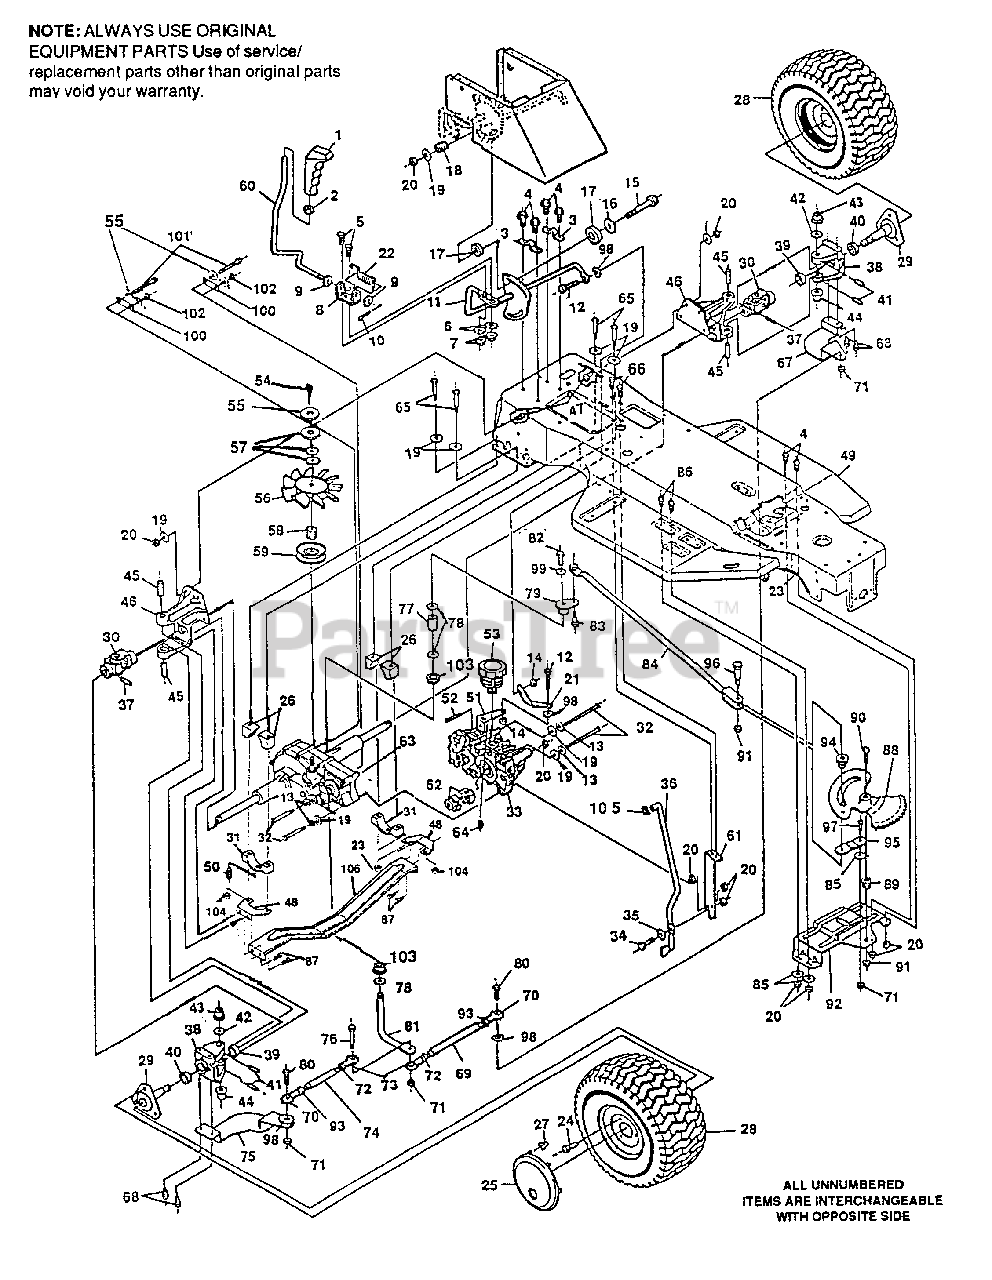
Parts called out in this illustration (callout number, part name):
1	Handle, Deck Engage Lever
2	Nut, 1/2-13 Jam
3	Bracket, Clutch/Brake Arm
4	Screw, 5/16-18 x 1/2 In.
5	Screw, 1/4-20 x .62 In.
6	Flatwasher
7	Nut, 1/4-20
8	Bracket, Shift
9	Washer, Flat
10	Pin, Cotter
11	Shift Rod Assembly
12	Screw, 3/8-16 x 1-1/4 In
14	Nut, 3/8-16 Thd
15	Screw, 5/16-18 x 2 In
16	Washer, Flat
17	Washer, Friction
19	Washer, Flat
20	Nut, 5/16-18 Thd
21	Shift Link
22	Spring, Torsion
23	Trim
24	Screw, Hx Hd, 1/2-20 x 1/2 In
25	Hubcap, 8 In
26	Mounting Block
27	Clip, Hubcap
28	Tire and Wheel Assembly
28	Tire, 15X6.0X6
28	Valve System
29	Hub Assembly
30	U-Joint Assembly
31	Mounting Block
32	Screw, 5/16-18 x 4-1/2 In
33	Hydrostatic Pump
34	Shoulder Bolt
35	Washer
36	Rod- Relief Valve
37	Pin, Grooved, 1/4 x 1 1/2 In
38	Bracket, Steering Pivot, Outer
41	Pin, Spring 1/4 x 1 1/2 In
42	Washer, Flat
43	Bushing, Shouldered
44	Bushing, Shouldered
45	Pin, Steering Hinge
46	Bracket, Steering Pivot, Inner
47	Screw, Hx Hd , 5/16-18 x 1 In
48	Bracket, Transaxle Mounting
49	Main Frame
50	Screw, #10-32 x 1 /4 In
51	Armspeed Control
52	Pin, Spring
53	Reservoir, Hydro
54	Screw, 1/4-20x.62 Hhc
55	Washer, Split Lock
57	Washer, flat .28x1.38x.07
58	Nut, Pulley 1/2-20 and 1/4-20
59	Pulley, Assy. Hydro
61	Stabilizer Bracket
63	Transaxle
65	Screw, 5/16-18x2 50 Hhc
66	Screw, 5/16-18x 63 Hhc
67	Arm, Rear Wheel Steer, L.H.
68	Screw, 3/8-16x1 00 Wahhtap Blk
69	Tie Rod, L.H.
70	Tie Rod End, L.H.
71	Nut, Hex, Ctrlk, 3/8-24
72	Nut, Hex Jam, 3/8-24
74	Tie Rod End, R.H.
75	Arm, Rear Wheel Steer, R.H.
76	Screw, 3/8-24 x 1 3/4 In
78	Washer, Flat 49/64 In
79	Steering Pivot
80	Screw, 3/8-24 x 1 1 /4 In
81	Shaft, Steering Pivot
82	Screw 5/16-24 x 1 In
83	Bolt, Shoulder 3/8-24
84	Rod Assembly, Rear Wheel Steer
85	Washer, Flat 3/8 In
86	Screw, Self-Tap 5/16-18 x 3/8 In
87	Screw, 5/16-18x 88 Wahhtap
88	Assembly Sector Gear
89	Bushing, Sector Gear
90	Screw, 1/2-20 x 2 3/8 In
91	Nut, Hx, Ctrlk 1/2-20
92	Plate, 4-Wheel Steer Pivot
93	Nut, Jam 3/8-24
94	Cam Yoke Roller
95	Arm, Roller Swing
96	Shoulder Bolt, Cam Roller
97	Shoulder Bolt, Cam Follower Arm Pivot
98	Washer, Split Lock
99	Washer Flat
100	Bracket, Rear Pivot
101	Screw 1/4-20 x 3/4 In
102	Nut 1/4-20
103	Bearing Spindle
104	Nut, 5/16-18 Locknut
105	Cap, Memory Rod .38 ID x .75
106	Hydro Brace
